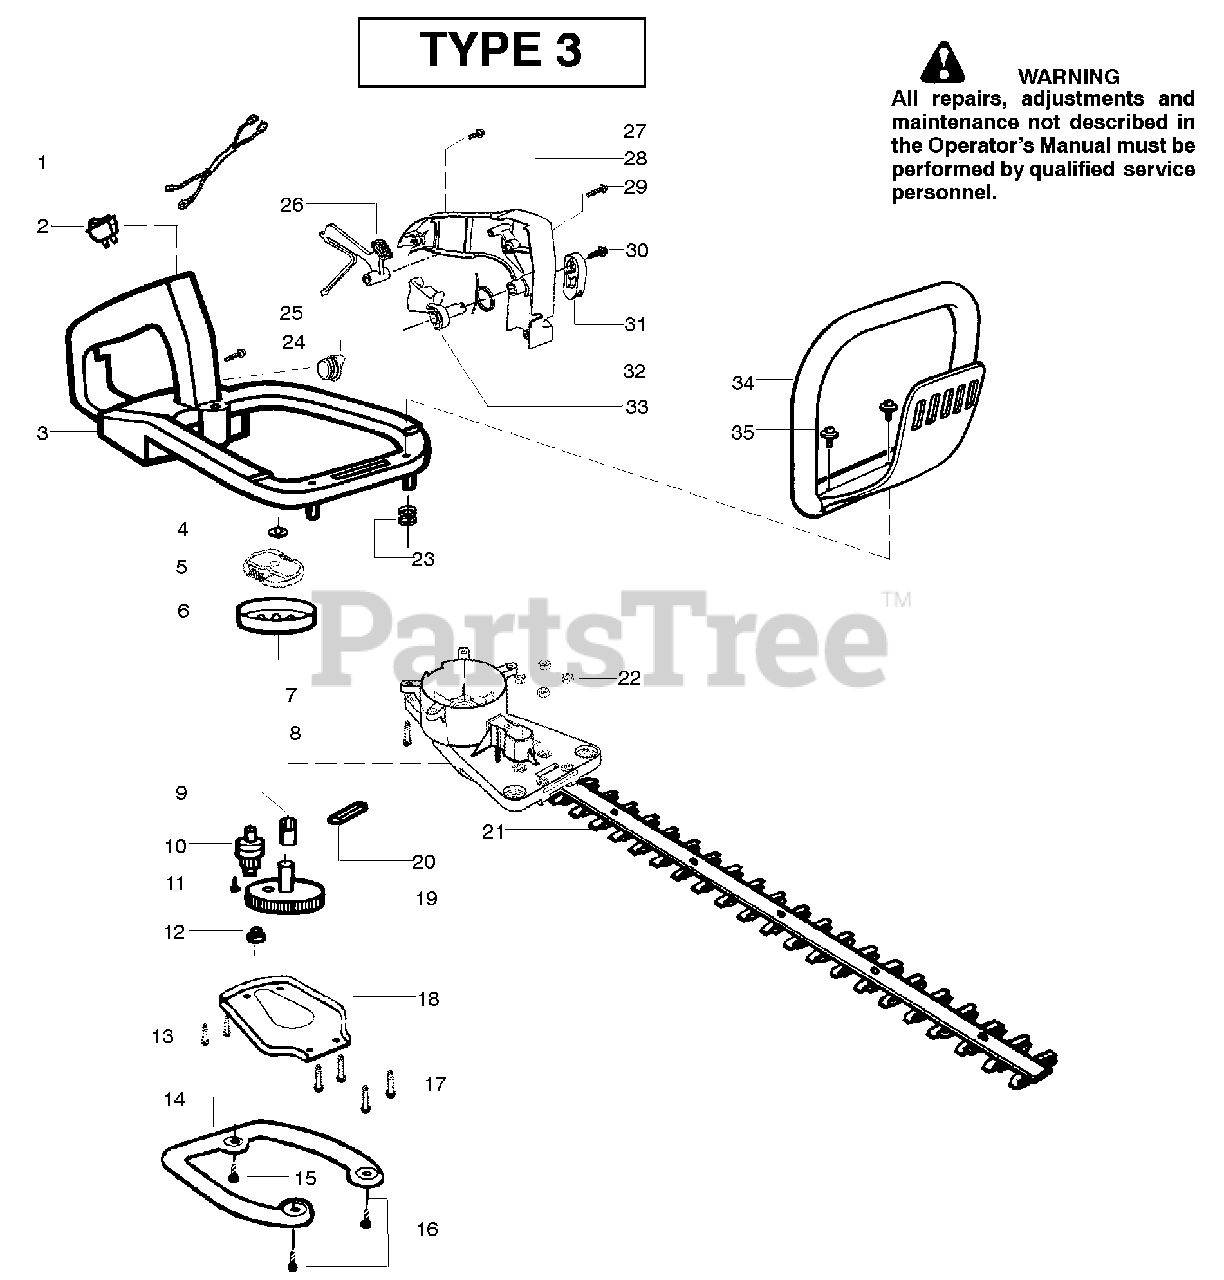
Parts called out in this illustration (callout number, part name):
1	Assy-Leadwire/Switch
2	Switch-Ignition
3	Assy-Rear Handle & Tank
4	Washer-Clutch
5	Kit-Clutch Assy.
6	Assy-Drum
7	Assy-Gear Box
9	Bearing-Gear
10	Assy-Pinion
11	Screw
12	Bushing-Blade
14	Plate-Isolator
18	Cover-Gear Box Plate
19	Kit-Drive Gear Ass'y.
20	Seal-Blade (Felt)
21	Assy-Blade 19"
24	Assy-Fuel Cap
26	Lockout-Throttle
28	Kit-Handle Cover
31	Lever-Trigger
32	Spring-Trigger
34	Handle-Front
